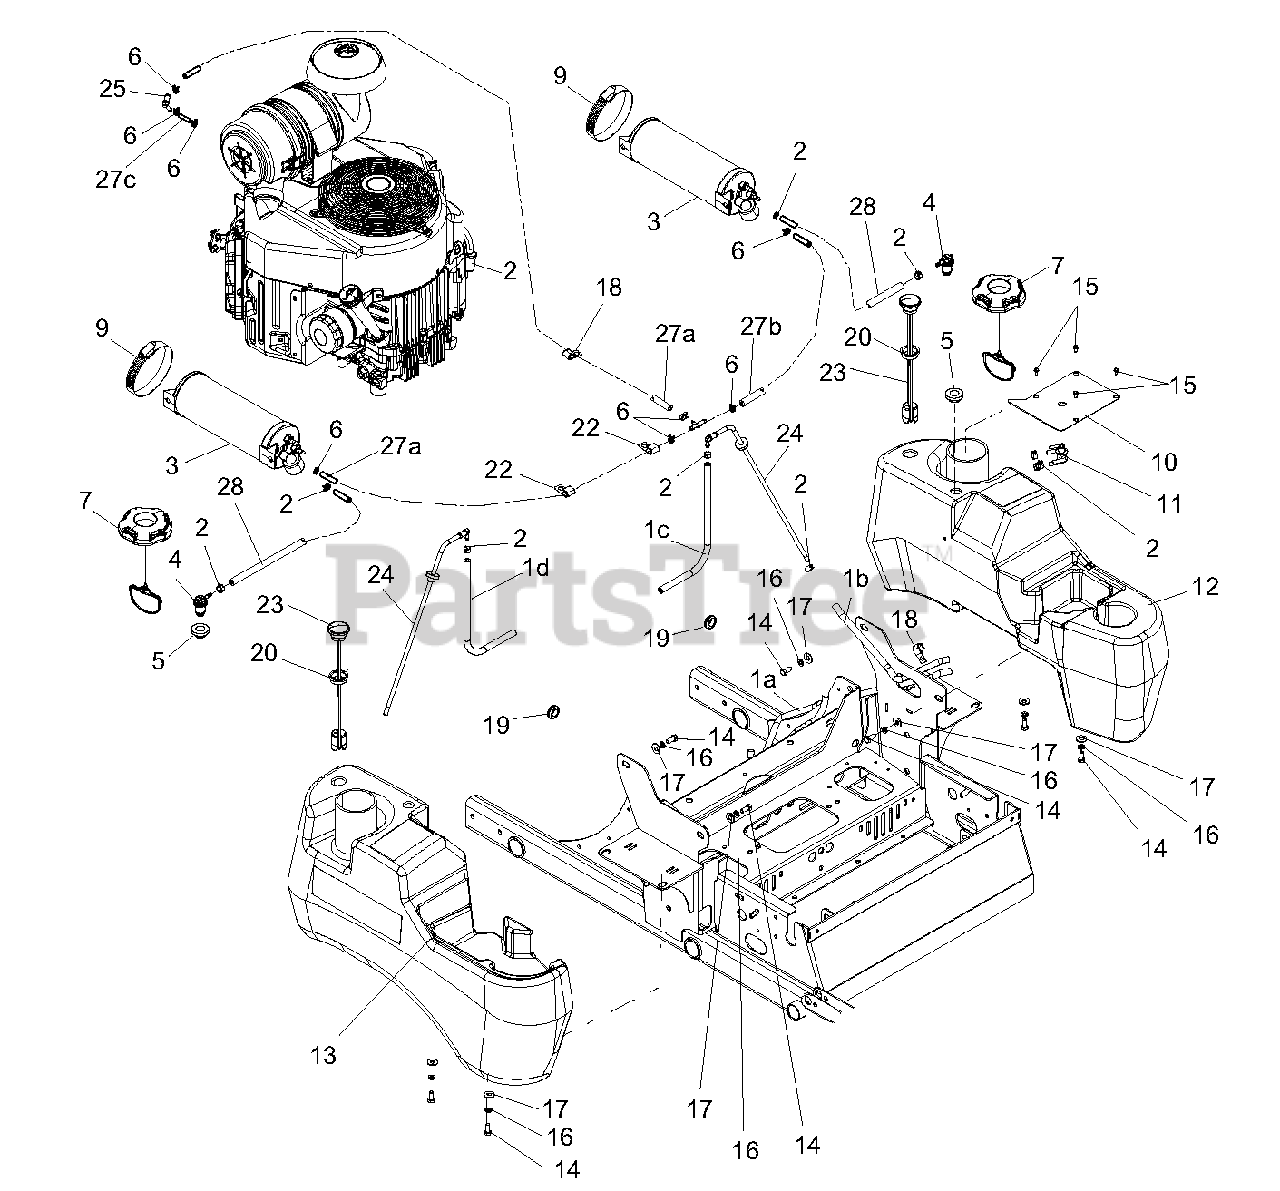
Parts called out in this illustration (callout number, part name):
2	CLAMP, FUEL LINE
3	CANISTER, CARBON 9.3G CAP
4	VALVE, COMBINATION
5	GROMMET, REMOTE VENT NITRILE
6	CLAMP - HOSE, SPRING .188
7	CAP, FUEL NONVENT AUTOLOCK
9	CLAMP - HOSE WORM 2.3/3.2 SS #44
10	PLATE, FUEL VALVE MOUNTING
11	VALVE, FUEL
12	TANK, LH LARGE FUEL (INCLUDES 20 & 23)
13	TANK, RH LARGE FUEL (INCLUDES 20 & 23)
14	BLT-HEX .31-18X.75 GR5 YWZC
15	SCR, HWH 10-24x.38 STAINLESS
16	WSHR-LK .31X.078 REG YWZC
17	WSHR-FL-STL.38X.875X.083 YWZC
19	GROMMET, RUBBER
20	GROMMET, FUEL GAGE
22	ROUTING CLIP (1/2" ID)
23	GUAGE, REMOTE FUEL, 12"
24	ASSEMBLY, LARGE TANK FUEL PICKUP
25	90 DEG 3/16" HOSE ELBOW
26	ASSM, VAPOR LINE (CARB) (Includes 6, 25, 27a, 27b 27c, and 28)
28	HOSE, .25 LOW-PERM BULK GAS
